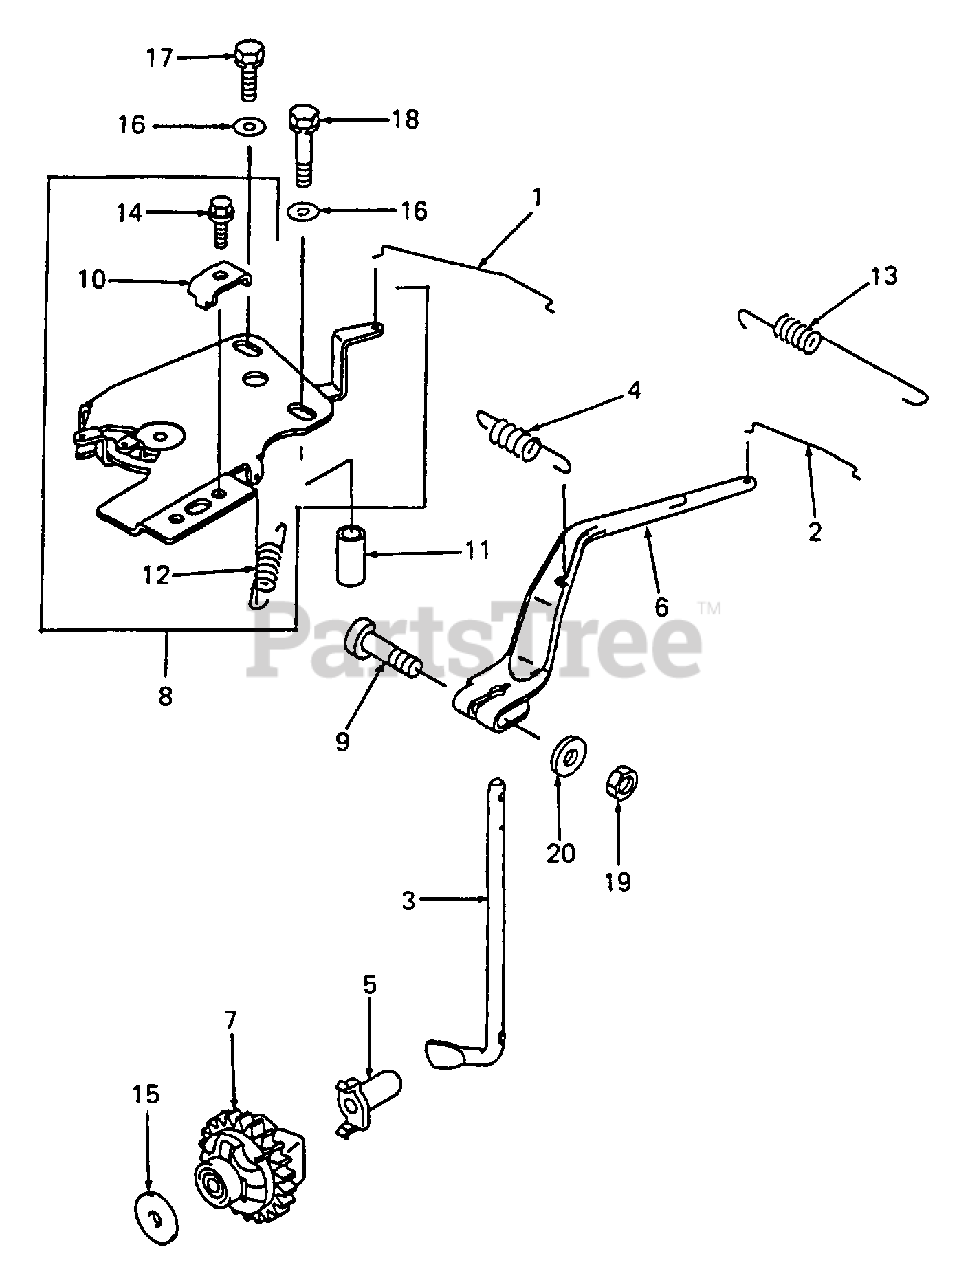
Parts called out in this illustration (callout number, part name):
1	Linkage, Choke
2	Linkage, Governor
4	Spring, Governor
5	Sleeve
6	Arm, Governor
7	Governor Assy
8	Panel, Control
11	Collar, 6.8 x 10 x 20.5
13	Spring
15	Washer, 6.2 x 20 x 0.5
17	Bolt, 6 x 16
18	Bolt, Upset, WS, 6 x 35
19	Nut, 6 MM
20	Washer, Plain, 6 MM
